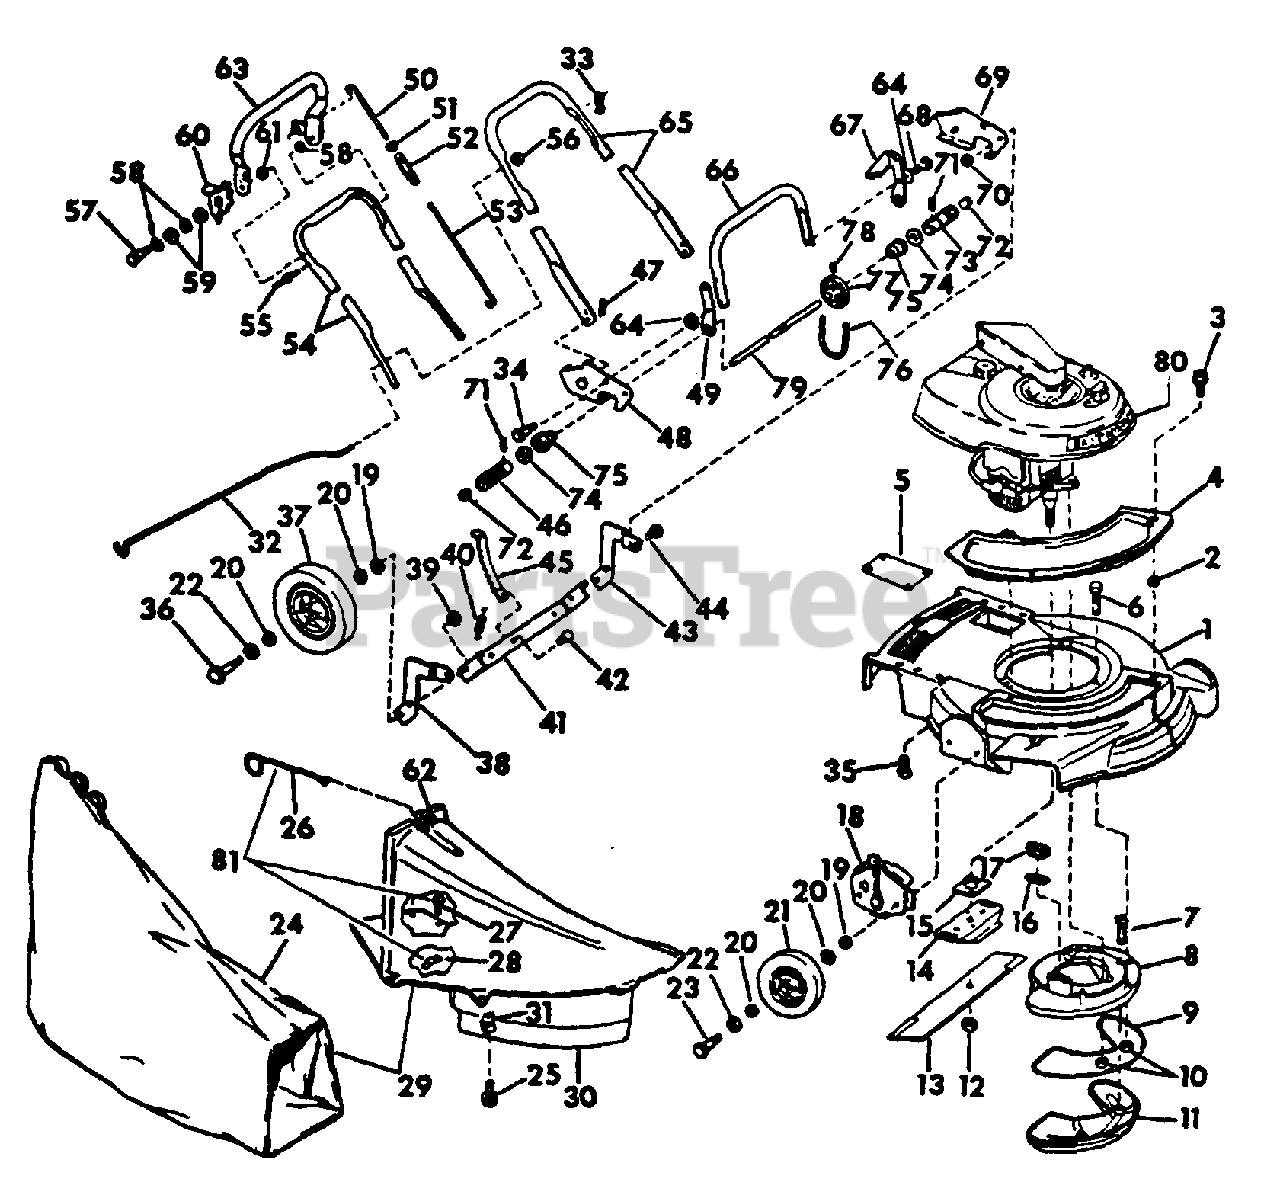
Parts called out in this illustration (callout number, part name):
1	HOUSING ASSY, 21 IN.
2	SCREW, 5/16-18 X 1-5/8 TYPE 8 HEX-HD CAP
2	NUT, GROMMET
3	SCREW, HEX-HD
4	COVER, CHUTE OPENING
5	COVER, POCKET
6	SCREW, MUFFLER PLATE TO HSG
7	SCREW, MUFFLER TO MUFFLER PLATE
8	PLATE W/SCREW, MUFFLER
9	GASKET, MUFFLER
13	BLADE, 21 IN
14	STIFFENER, BLADE
15	COLLAR & PLATE
16	GASKET, EXHAUST
17	SLEEVE, EXHAUST GASKET
18	ADJUSTMENT, HEIGHT
20	WASHER, FELT
21	WHEEL & TIRE, 6 IN.
22	WASHER, WHEEL BOLT HD
23	BOLT, WHEEL FRT SHOULDER
26	GUARD, WHEEL
29	CHUTE ASSY
30	SKIRT ASSY, CHUTE
32	ROD, GRASS BAR
34	BOLT, SHOULDER
35	SCREW, HANDLE BRACKET
36	BOLT, REAR WHEEL
37	WHEEL AND TIRE, 8 IN.
38	BRACKET, WHEEL RIGHT REAR
39	NUT, REAR WHEEL BOLT
40	SPRING, HEIGHT ADJ
43	BRACKET, WHEEL REAR LH
44	BOLT, SHOULDER
45	LEVER, HEIGHT ADJ
46	ROLLER, DRIVE RIGHT
48	BRACKET, HANDLE RIGHT
49	BRACKET, BRG CARRIER RH
50	ROD, CONTROL UPPER
53	ROD, CONTROL LOWER
54	HANDLE, CENTER
55	PIN, LOCKOUT
56	NUT, CENTERLOCK
59	WASHER, WAVE
60	CLIP, LOCKOUT
63	HANDLE & GRIP
65	HANDLE, LOWER
66	LINK, CONNECT
68	BOLT, SHOULDER
69	BRACKET, HANDLE LH
71	PIN, ROLLER TO SHAFT
72	PLUG, ROLLER GREASE
73	ROLLER, DRIVE LH
74	WASHER
75	SLEEVE & BEARING
76	V-BELT, DRIVEN
77	PULLEY W/SET SCREW, DRIVEN
80	ENGINE, IH
81	GUARD ASSY, WHEEL
